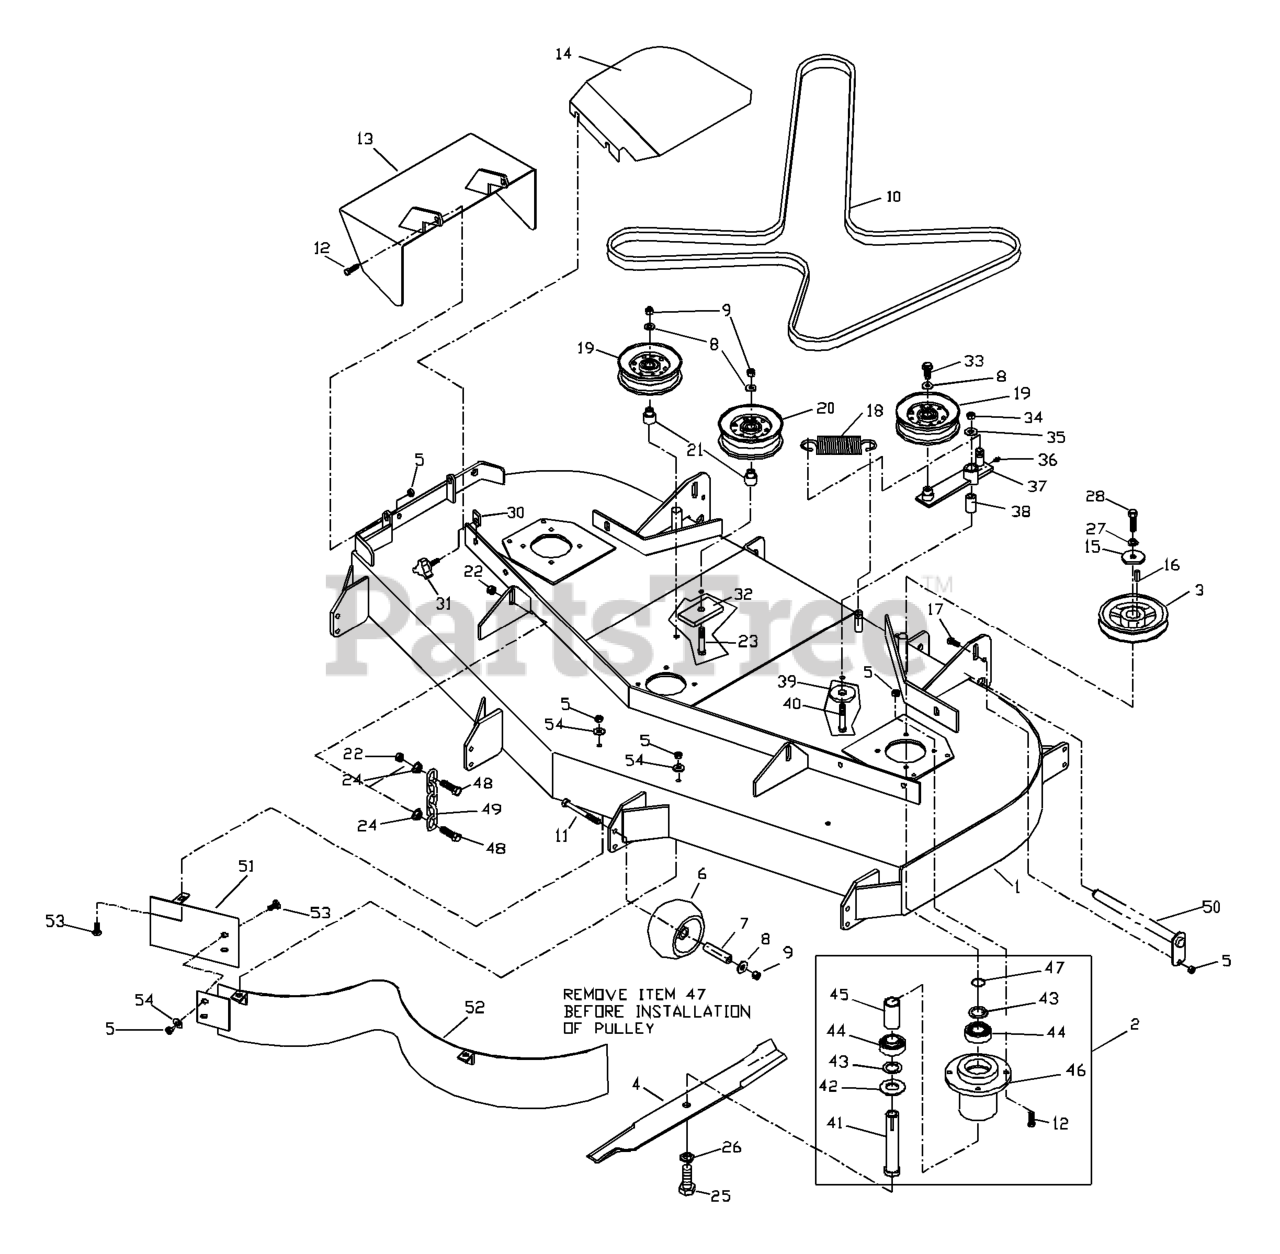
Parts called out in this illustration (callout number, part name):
1	DECK W/DECALS 61" HUS
1	DECK W/DECALS 52" HUS WSL
2	HOUSING ASM.
3	PULLEY 52" DECK
4	BLADE OEM 21" (61" DECK)
4	BLADE OEM 18"
5	NUT 5/16C CENTERLOCK
6	ANTI-SCALP ROLLER
8	WASHER 3/8 FLAT
9	NUT 3/8C CENTERBLOCK
10	DECK BELT 61
10	BELT, DECK
11	HCS 3/8C X 3 1/2
12	HCS 5/16C X 1
13	DISCHARGE CHUTE
14	61 B.S.PAINTED, RT
14	52 B.S.PAINTED,RT
15	WASHER, CRANKSHAFT
16	KEY 1/4 SQ X 1 1/8
17	HCS 5/16C X 3/4
18	DECK SPRING
19	IDLER PULLEY
20	IDLER PULLEY (TALL)
21	IDLER BUSHING
22	NUT 7/16C CENTERLOCK
23	HCS 3/8C X 2 1/2
24	NUT 7/16C WHIZ
25	HCS 5/8F X 1 1/4
26	LOCKWASHER 5/8
27	WASHER 7/16 LOCK
28	HCS 7/16F X 1 1/2
29	61 B.S.PAINTED, LT ORANGE
29	52 B.S.PAINTED, LT
30	U-CLIP 5/16-18 NUT RETAINER
31	KNOB W/STUD
32	SUPPORT PLATE
33	4CS 3/8C X 1 SERRATED HEAD
34	NUT 1/2-13 HEX NYLOC ZD
35	WASHER 1/2 FLAT
36	ZERK
38	PIVOT BUSHING
39	WASHER, SUPPORT
40	HCS 1/2C X 3 1/4
42	MACHINERY BUSHING 10 GA.
43	BUSHING.MACHINE.18.GAUGE
44	BEARING
46	HOUSING, DIE CAST
48	HCS 7/16C X 1 1/2
49	LIFT CHAIN
51	CENTER BAFFLE - 52"
51	CENTER BAFFLE - 61
52	MAIN BAFFLE 52"
52	MAIN BAFFLE - 61" BLK
53	CARRIAGE BOLT 5/16C X 5/8"
54	WASHER 5/16 FLAT
